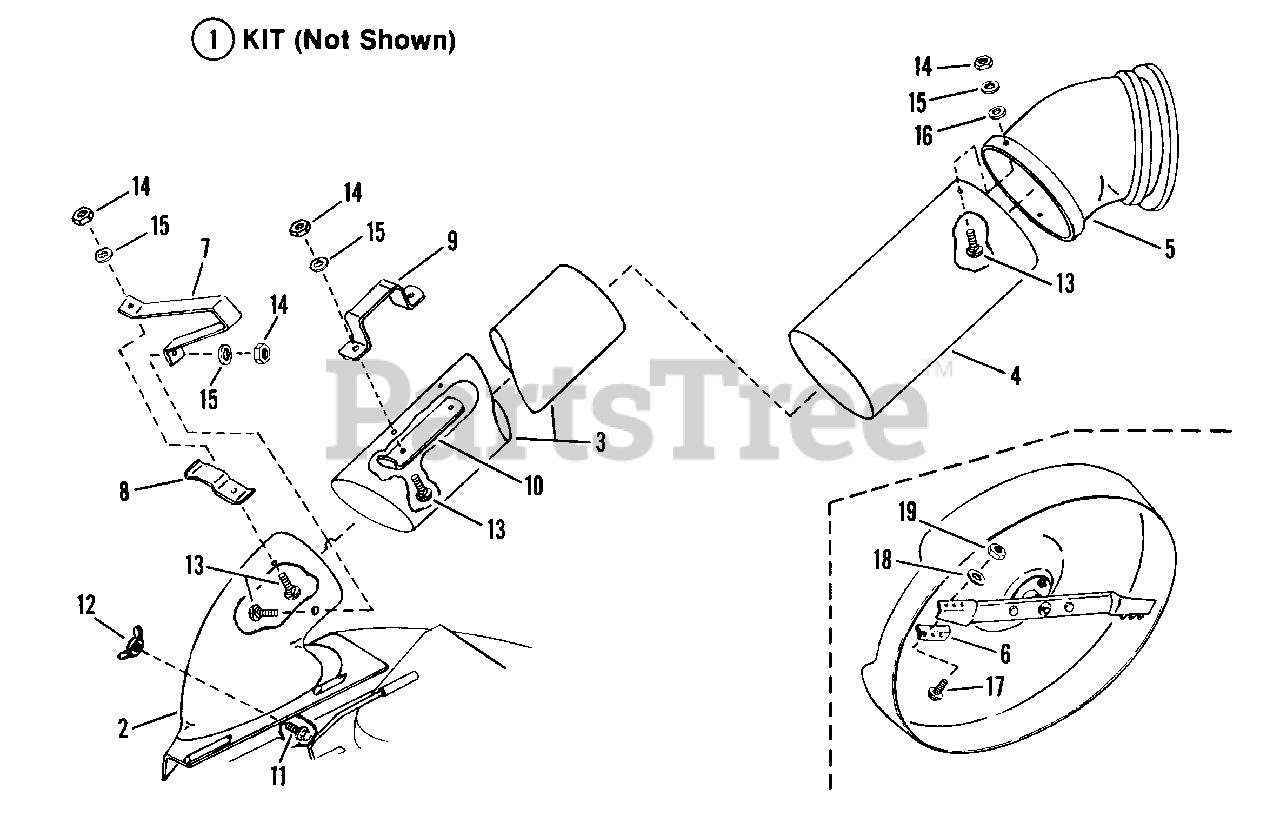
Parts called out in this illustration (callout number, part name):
2	ADAPTER, Deck
3	TUBE, Grass (8" Diameter)
4	TUBE, Grass (10" Diameter)
5	ELBOW, Grass Tube
6	KIT, Air-Lift
7	BRACKET, Stand-Off
8	LATCH, Tube
9	HANDLE, Tube
10	BASE, Tube Handle
11	CARRIAGE BOLT, 5/16-18 x 1/2"
12	WING-NUT, 5/16-18
13	CARRIAGE BOLT, 1/4-20 x 3/4"
14	NUT, 1/4-20 Hex
15	LOCKWASHER, 1/4 Internal Tooth
16	WASHER, 5/16 SAE
17	SCREW, 5/16-24 x 21/32"
18	LOCKWASHER, 5/16 Internal Tooth
19	NUT, 5/16-24 Hex
